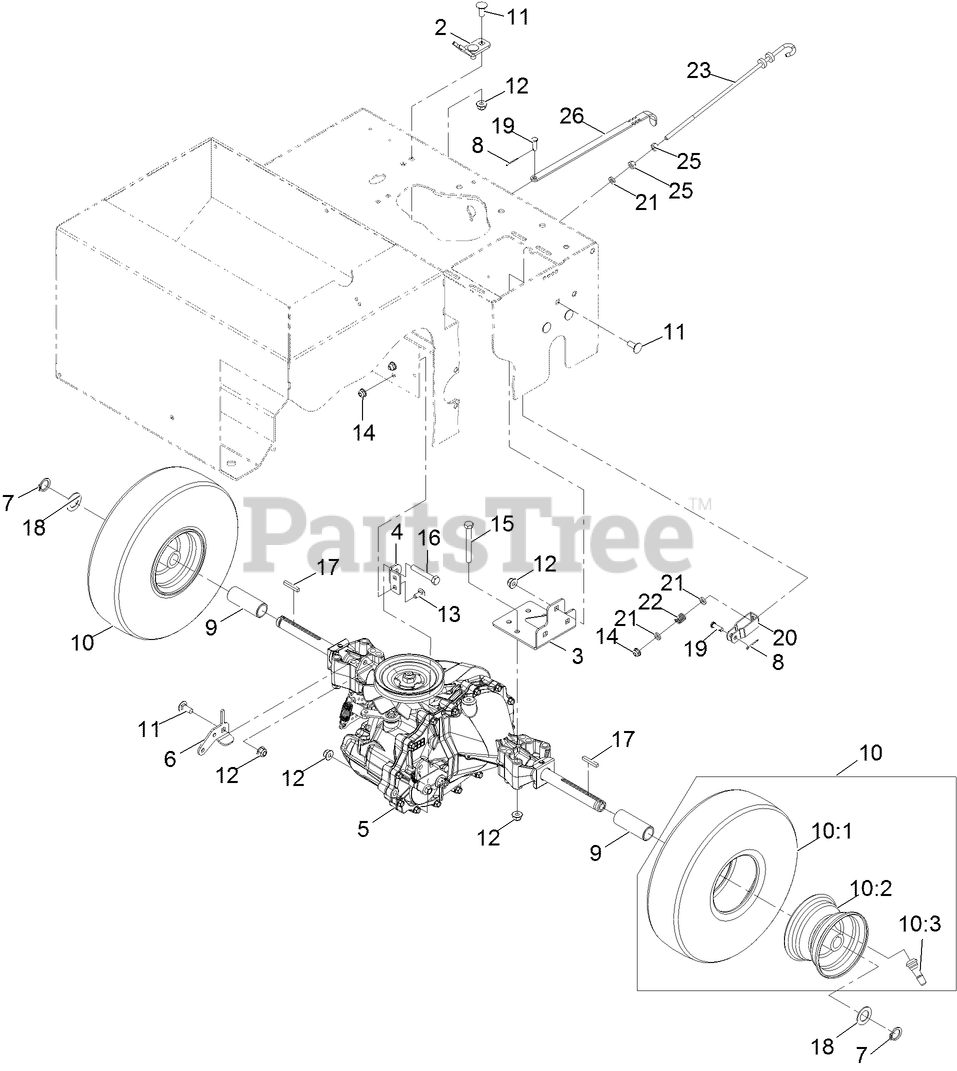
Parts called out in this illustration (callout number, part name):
2	BRACKET-CABLE
3	BRACKET-AXLE
4	BRACKET-TRANSAXLE, TORQUE
5	TRANSAXLE ASM
6	BRACKET-TRANSAXLE
7	RING-RETAINING
8	PIN-COTTER
9	SPACER
10	WHEEL ASM
10:2	WHEEL-RIM
10:3	VALVE
11	Bolt-Carriage 5/16-18 x 3/4 short neck
12	Nut-Nyloc 5/16-18 Flg
13	Bolt-Carriage 1/4-20 x 5/8
14	Nut-Nyloc 1/4-20 Flg
15	Screw-HH 5/16-18 x 2 3/4
16	Screw-HH 5/16-18 x 2
17	Key-Machine 3/16 x 3/16 x 1 1/4
18	WASHER
19	Pin-Clevis 1/4 x 3/4
20	CLEVIS
21	Spacer
22	SPRING-COMPRESSION
23	ROD-BRAKE
25	Nut-Hex 1/4-20
26	LEVER-BYPASS
